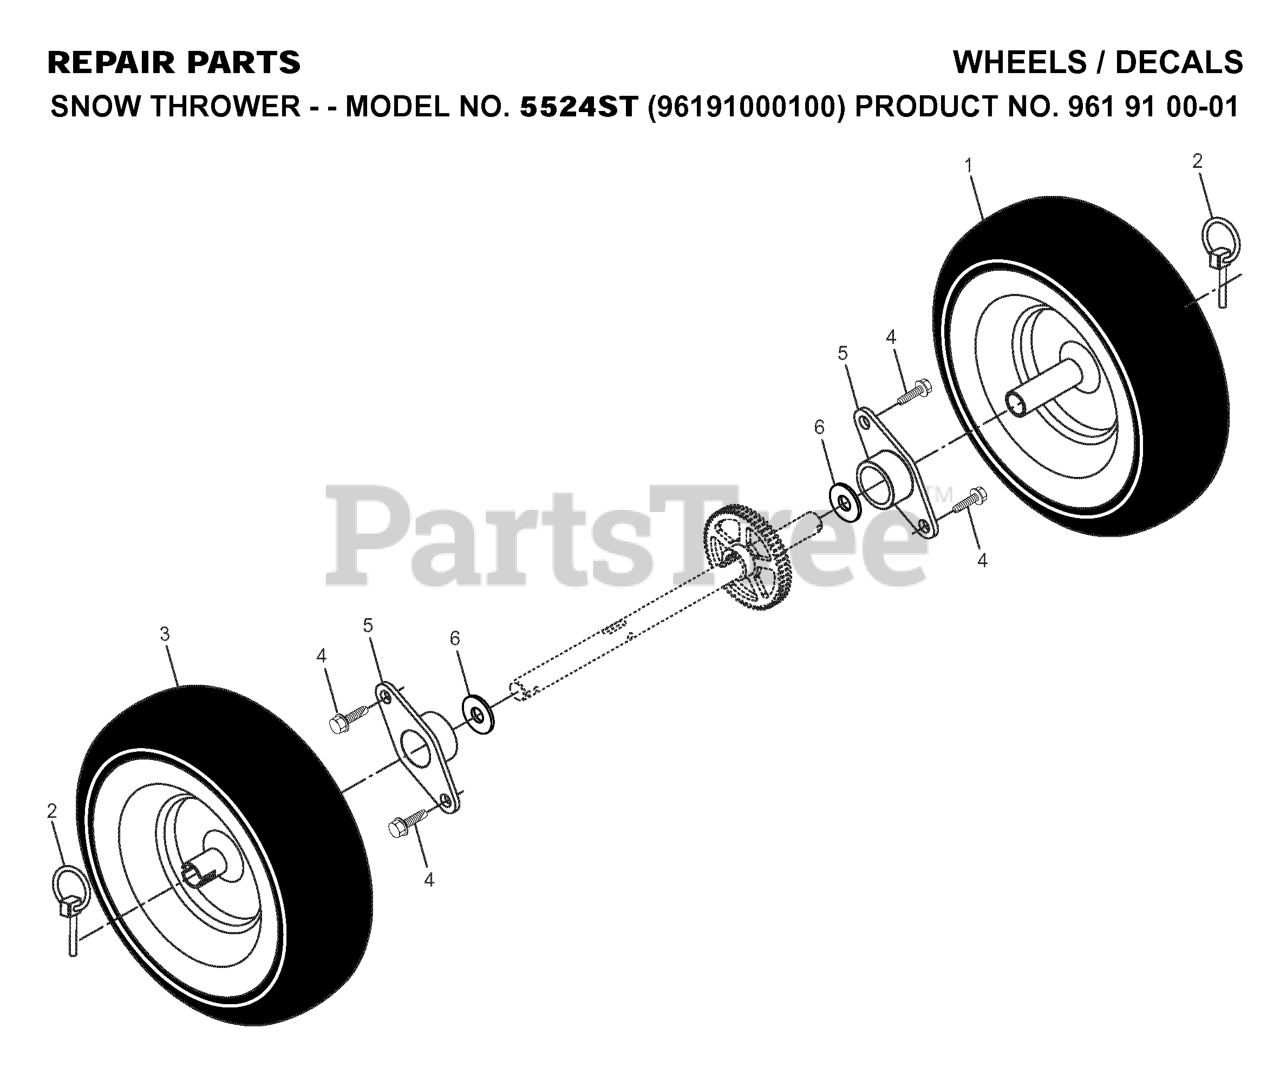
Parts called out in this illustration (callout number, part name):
1	WHEEL.ASM.LT.16"GRY.XTRAC
2	PIN KLIK, 1/4
3	WHEEL.ASM.RT.16".GRAY.SN
5	BEARING, AXLE
6	WASHER TRUST 1"
